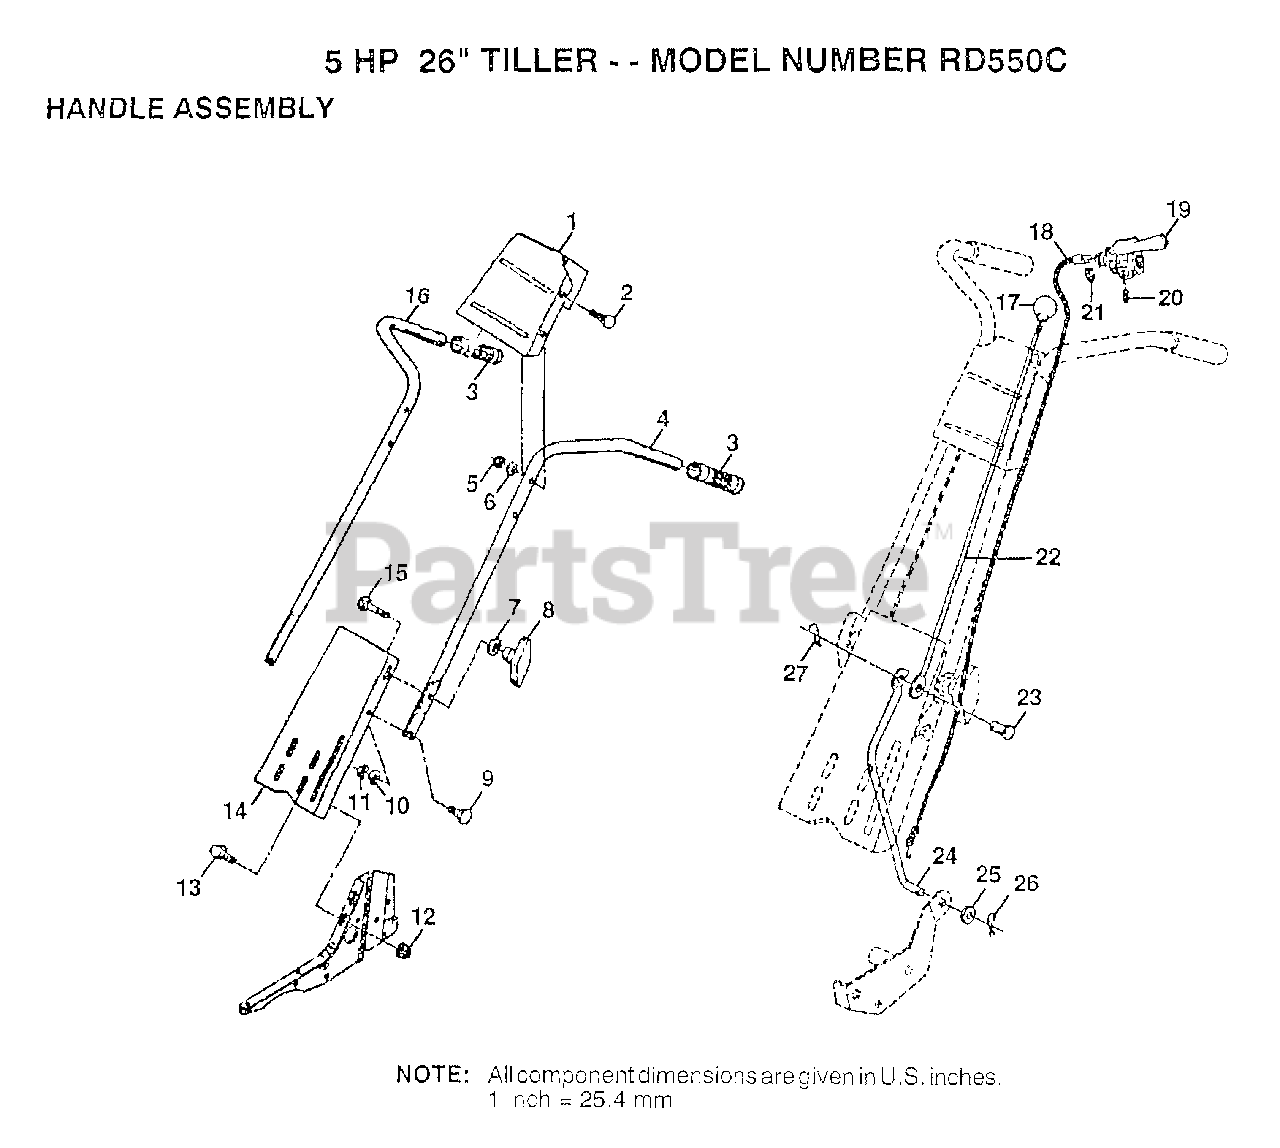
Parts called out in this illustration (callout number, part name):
1	HANDLE BRACKET
2	BOLT
6	WASHER
7	WASHER
10	LOCKWASHER
11	NUT.HEX.5/16-18
12	NUT
13	BOLT
15	BOLT
17	KNOB T(3/8 HOLE)
18	CABLE CLUTCH T
19	CONTROL LEVER TI
20	SCREW
21	E-RING
22	ROD REVERSE TI
23	RIVET.RD.HD.DRILL
24	REVERSE ROD TI
25	WASHER
26	COTTER PIN
